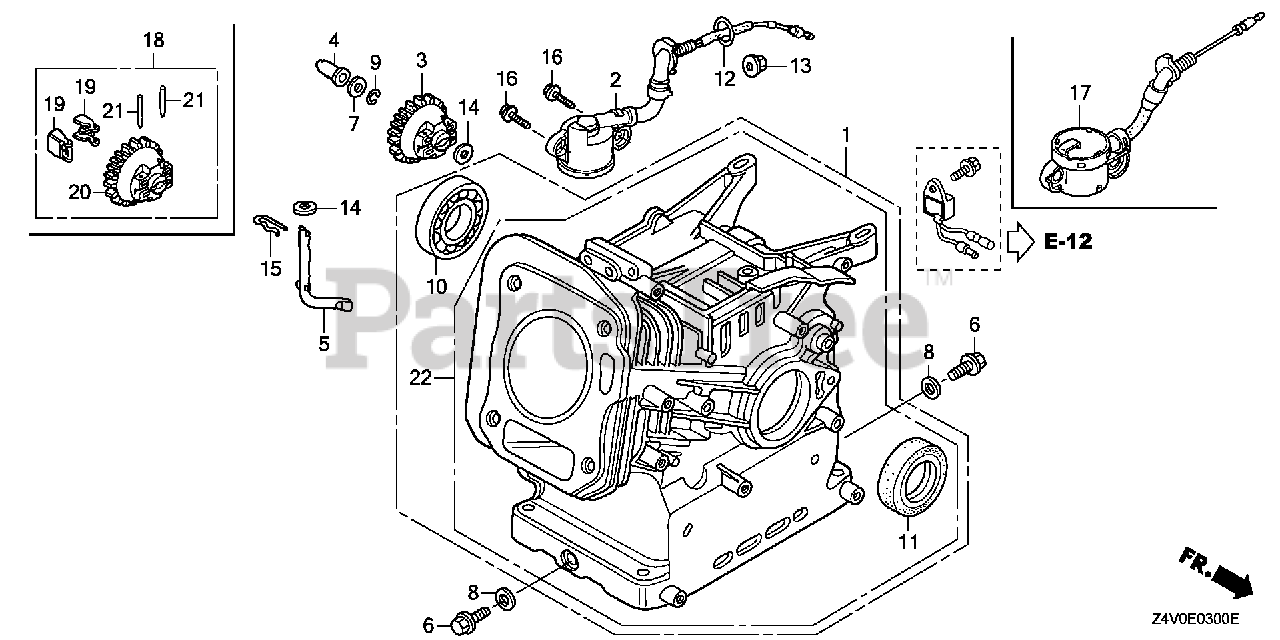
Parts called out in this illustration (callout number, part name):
3	GOVERNOR ASSY.
4	SLIDER, GOVERNOR
5	SHAFT, GOVERNOR ARM
6	BOLT, DRAIN PLUG
7	WASHER, THRUST (6MM)
8	WASHER, DRAIN PLUG (10.2MM)
9	CLIP, GOVERNOR HOLDER
11	OIL SEAL (25X41X6)
11	OIL SEAL (25X41X6) (ARAI) (NOT AVAILABLE)
12	O-RING (14MM) (ARAI) Use up to Engine SN 2949254.
12	O-RING (14MM) (NOK)
13	NUT, FLANGE (10MM)
14	WASHER, PLAIN (6MM)
15	PIN, LOCK (8MM)
16	BOLT, FLANGE (6X12) Use up to Engine SN 1543277.
17	SWITCH ASSY., OIL LEVEL
22	CYLINDER ASSY. (OIL ALERT)
